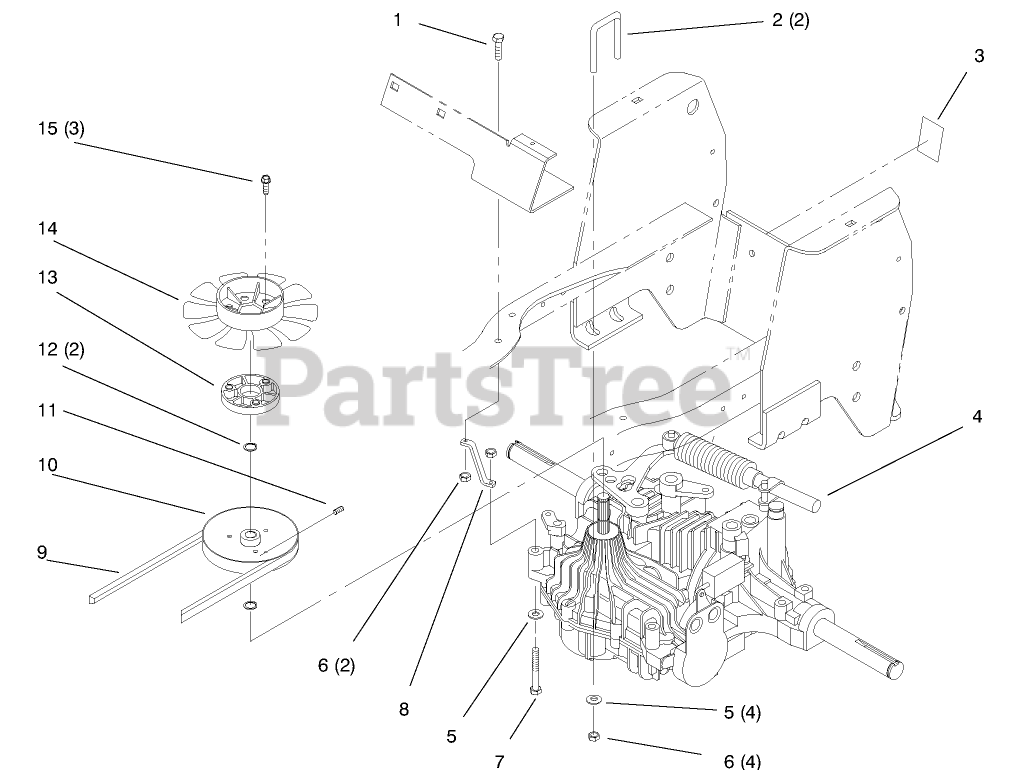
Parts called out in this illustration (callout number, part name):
1	SCREW-HH
2	U-BOLT
3	DECAL-VALVE, HYDRO
3	DECAL-BYPASS VALVE
5	WASHER-PLAIN
6	NUT-LOCK, NI
7	SCREW-HH
8	STRAP-TRQ HY
9	V-BELT, HYDRO
10	PULLEY-HYDRO TRANS
11	SCREW-HSH
12	RING-RETAINING
13	SPACER - FAN
14	FAN - HYDRO
15	SCREW-HWHTF
